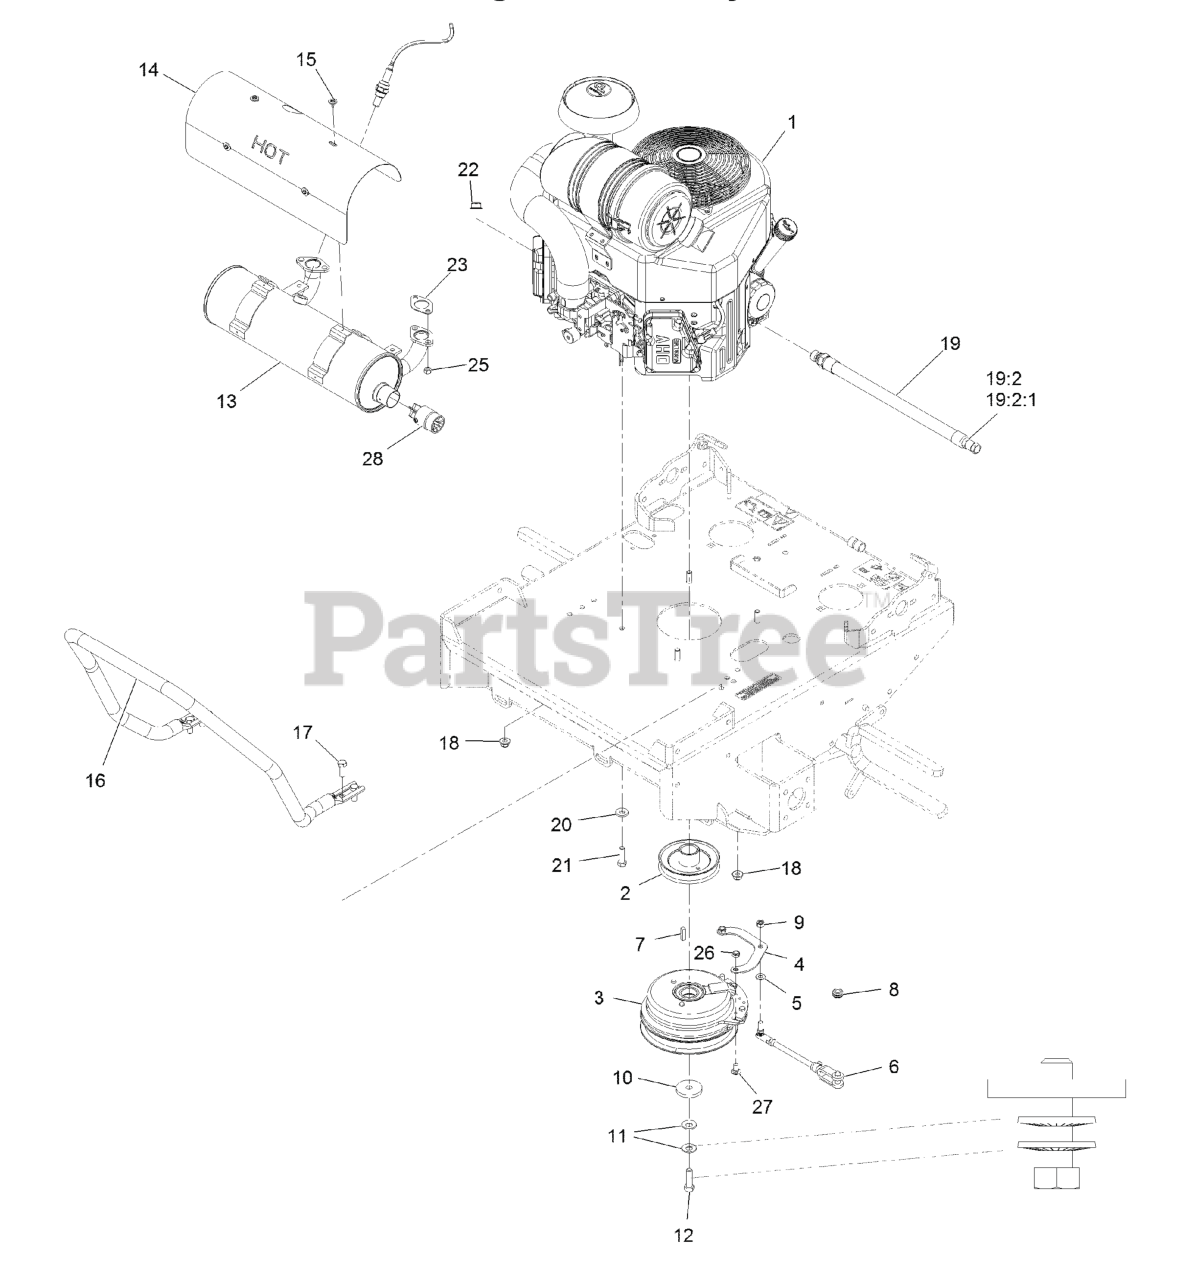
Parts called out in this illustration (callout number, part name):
2	SHEAVE W/ HUB
3	CLUTCH, 200 FT/LBS, 1.13
4	STRAP, CLUTCH
5	WASHER-PLAIN
6	ASM, CLUTCH ANCHOR
7	KEY
8	GROMMET
9	NUT-LOCK
10	WASHER-CLUTCH
11	WASHER-SPRING
12	BOLT-HEX, TAP
13	MUFFLER-TTX, EFI
14	SHIELD-MUFFLER,TTX EFI
15	SCREW-HH, THREAD FORMING
16	GUARD,AIR CLEANER
17	SCREW-HH
18	NUT-HF, NI
19	OIL DRAIN HOSE ASM
19:2	PLUG-HH
19:2:1	O-RING
20	WASHER-SPRING
21	SCREW-HH
22	NUT-HF, NI
23	GASKET-EXHAUST
25	NUT-FLANGE
26	NUT-LOCK, NI
27	SCREW-CARR
28	ARRESTOR,SPARK 1.375 DIA
